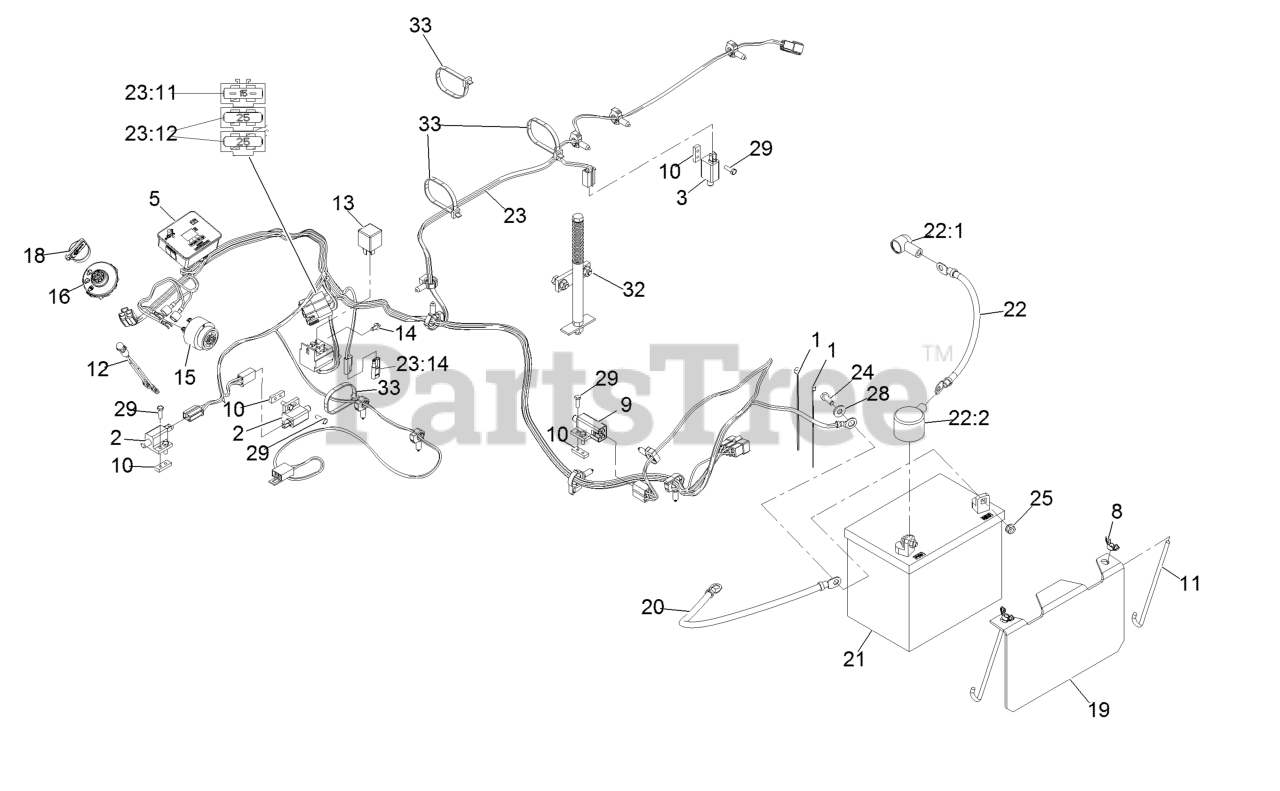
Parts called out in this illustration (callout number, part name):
1	Tie-Cable 5 1/2 (Small)
2	Switch-N.O.
3	Switch-N.C.
5	Hour Meter ASM
8	Wingnut-Nyloc 1/4-20
10	Plate-Tapped
11	Bolt-Holddown
12	Indicator-Red LED
13	Relay-12Vdc 40 Amp
14	Screw-HWH #10-24 X 3/8
15	Alarm-Dual Tone 12Vdc
16	Switch-Ignition
18	Key-Exmark Logo
19	Hold Down-Battery
20	Cable-Ground(-)
21	Battery (300 CCA, Wet)
22	Cable-Battery, Positive
22:1	Insulator-Solenoid
22:2	Insulator-Battery
23	Harness-Wiring
23:11	Fuse-Blade, 15 Amp
23:12	Fuse-Blade, 25 Amp
23:14	Cap-Plug
24	Screw-HH 1/4-20 X 3/4
25	Nut-Whizlock 1/4-20
28	Washer-1/4 Std
29	Screw-HH Machine 10-24 X 5/8
32	Hopper Switch Actuator ASM
33	Tie-Cable 7 15/16 (Large)
